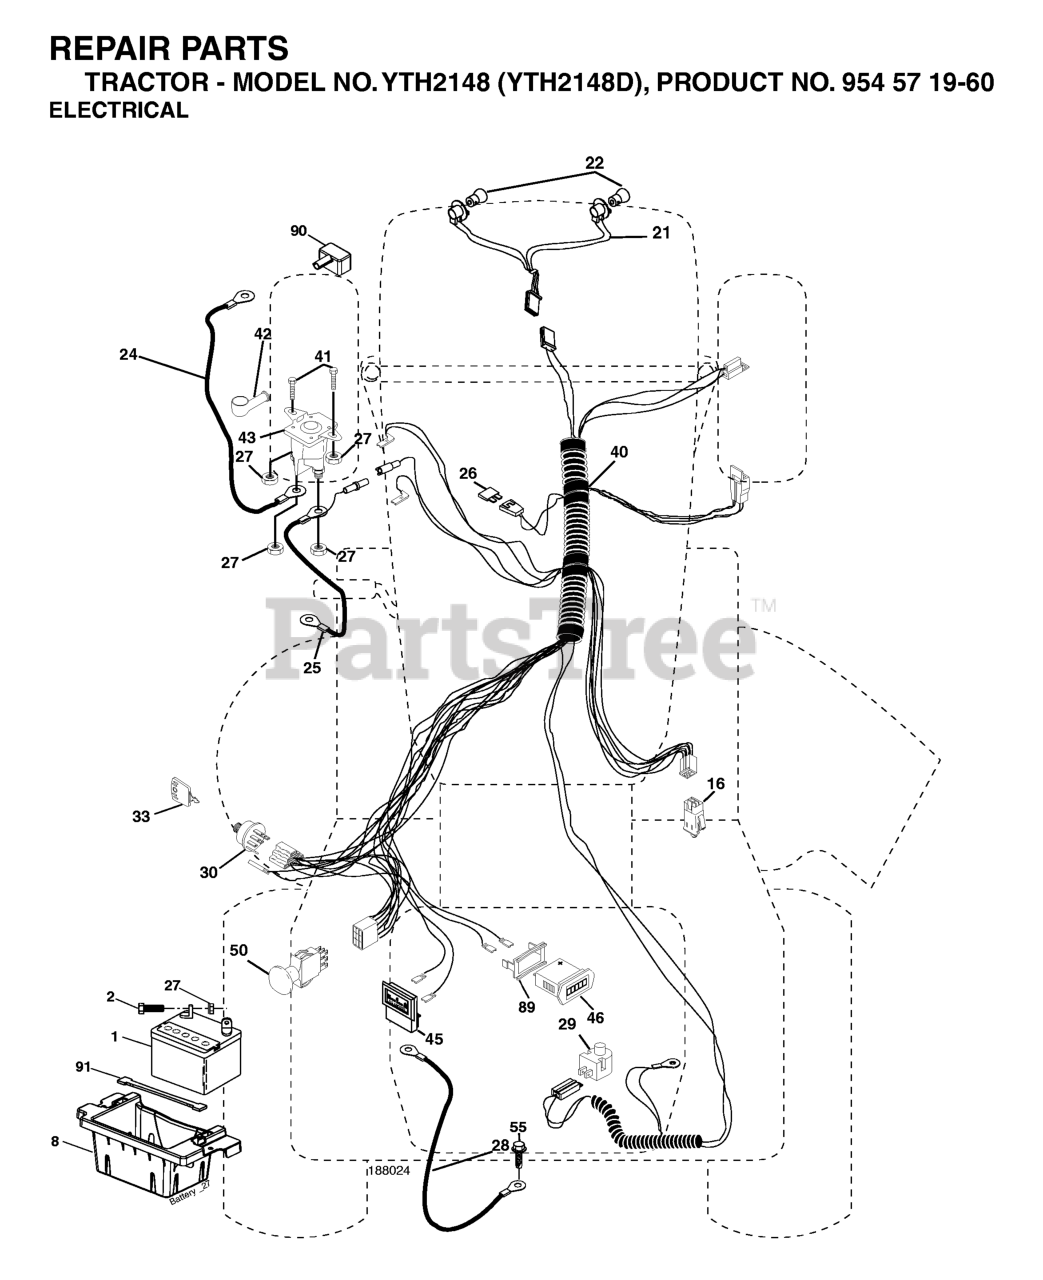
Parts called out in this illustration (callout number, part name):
1	BATTERY 12V .35 AMP
2	BOLT.HEX.1/4.X.3/4.DICHROMATE
8	BOX.BATTERY.MOUNT.FRONT.LT
10	BOLT 1/4-20 X 7.5
11	BATTERY HOLDDOWN FRONT MOUNT
12	NUT, PUSH NYLON 1/4" BATTERY
16	SWITCH INTERLOOK PUSH-IN
21	HARNESS ASSY LIGHT
24	BATTERY CABLE GT
25	CABLE BATTERY 6 GA 22" W/16W
26	FUSE 20AMP
27	NUT
28	CABLE GROUND 6 GA 21" 90T BLK
29	RP.SWITCH.PLUNGER.NC.GRAY
30	IGNITION SWITCH
33	KEY MLD GEN DELTA
40	HARNESS.IGNITION
41	BOLT
42	TERMINAL COVER
43	SOLENOID
46	HOUR METER
50	RP.PTO.SWITCH.8 TERMINAL.BLACK
55	Screw 5/16-18 x 1/2 Hex, Self Tapping 5/16-18 x 1/2
89	BRACKET SNAP-IN HOURMETER
90	COVER TERMINAL
91	STRAP.BATTERY.MOUNT.FRONT(2 2)
